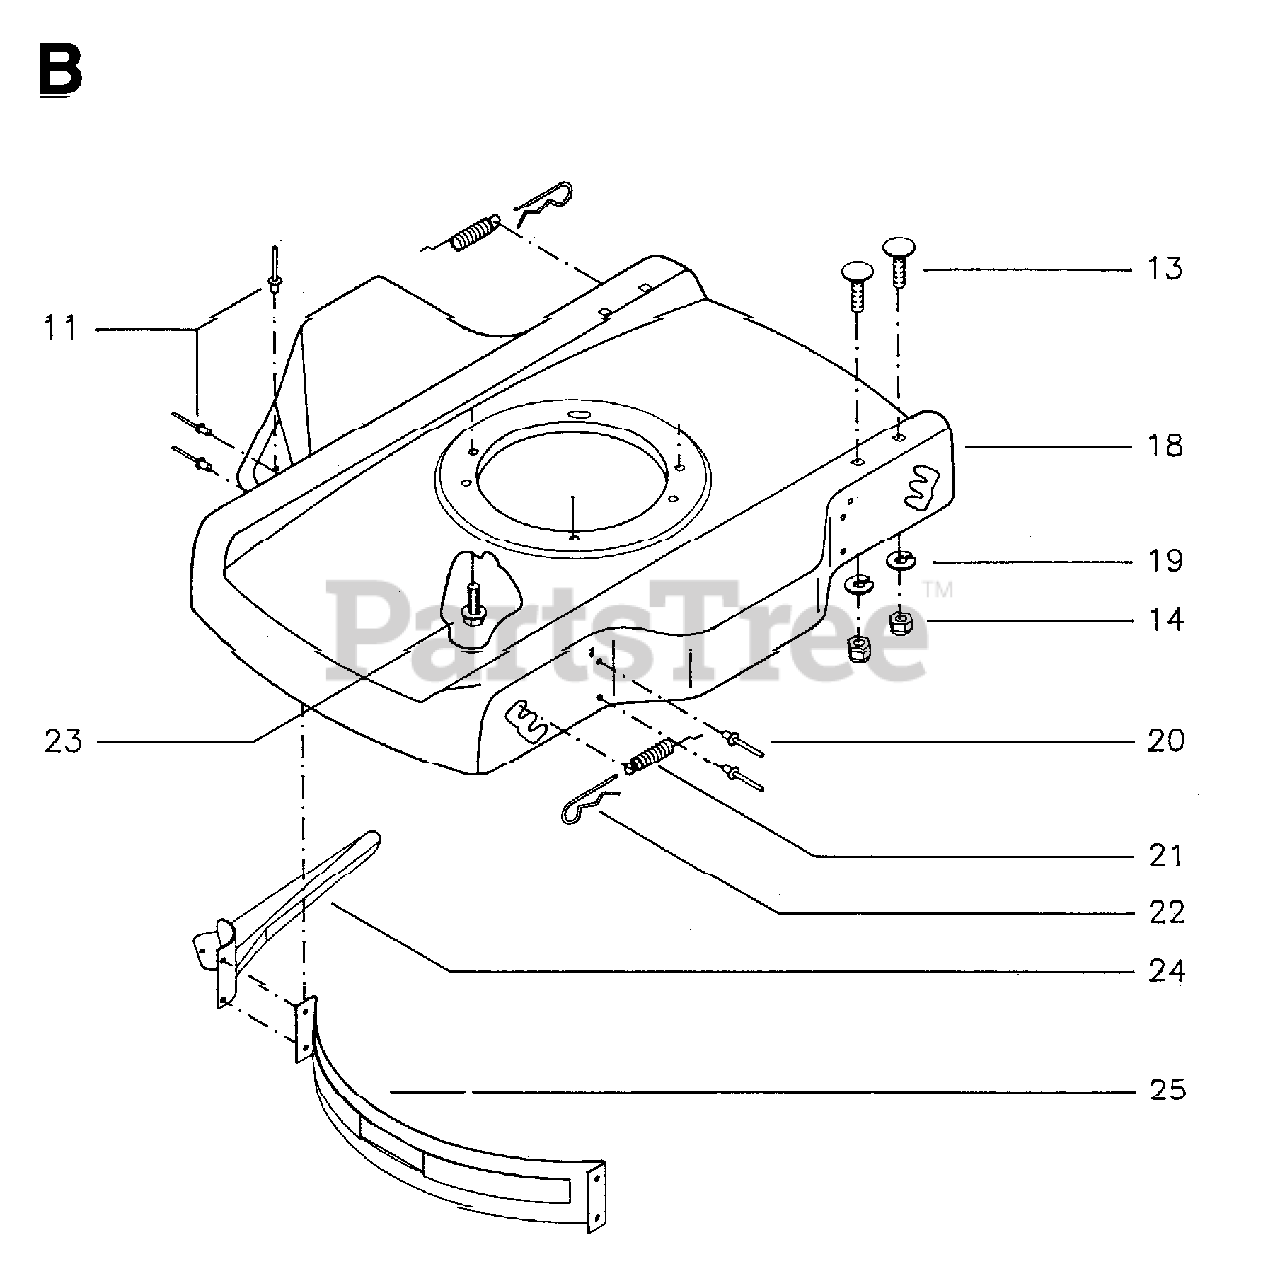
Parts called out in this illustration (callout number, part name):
11	REPL BY 516 92 38-00
14	NUT
19	SPRING WASHER
